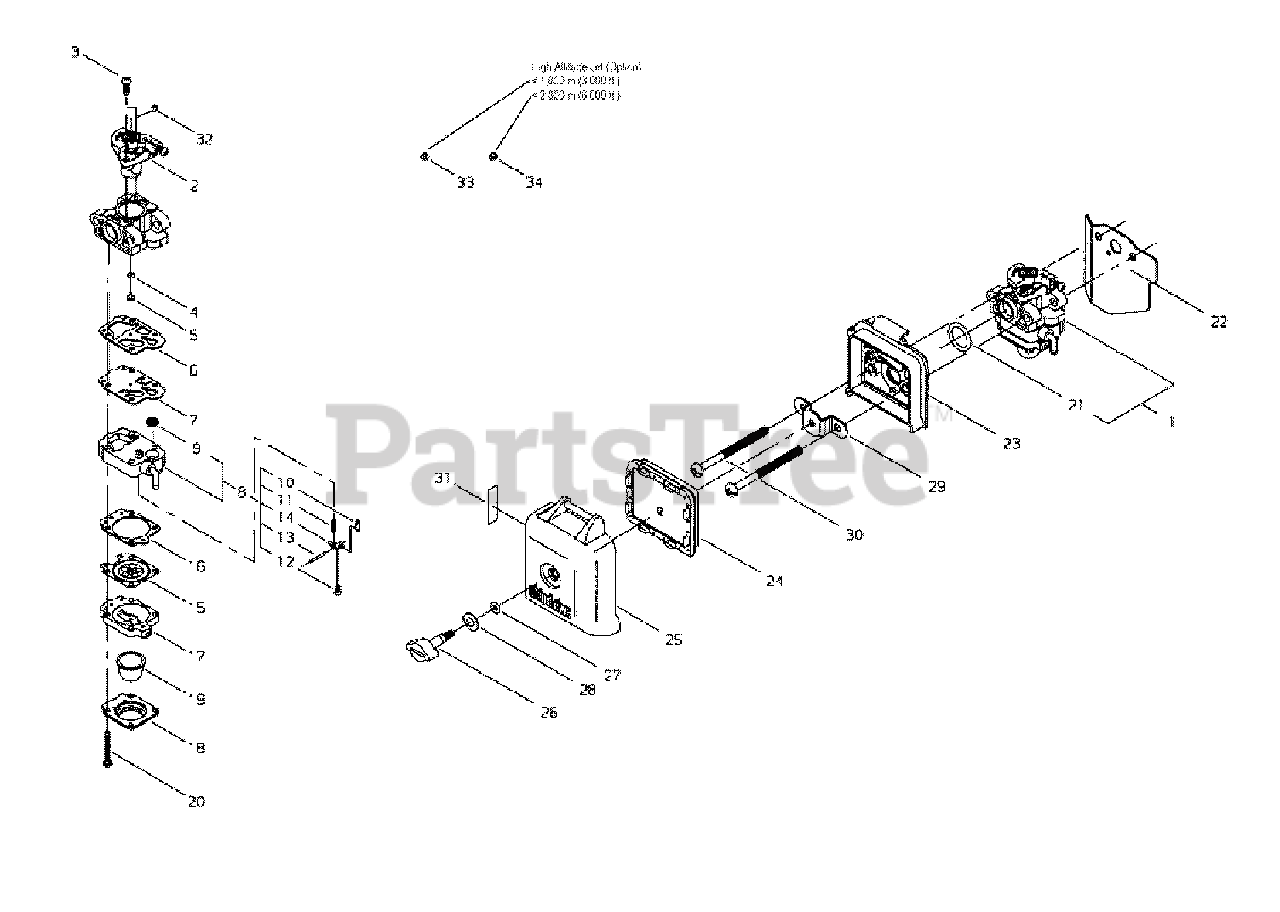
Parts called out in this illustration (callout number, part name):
1	CARBURETOR
2	VALVE, THROTTLE
3	SCREW
4	O-RING
5	JET, MAIN
6	GASKET, PUMP
7	DIAPHRAGM, PUMP
8	BASE, PURGE
9	STRAINER
10	VALVE, INLET NEEDLE
11	SPRING, METERING LEVER
12	SCREW, METERING LEVER PIN
13	PIN, METERING LEVER
14	LEVER, METERING
15	DIAPHRAGM, METERING
16	GASKET, METERING
17	BASE, PURGE
18	RETAINER, PURGE BULB
19	BULB, PURGE
20	SCREW, PUMP COVER
21	O-RING - 15
22	SHIELD, INTAKE
23	CASE, AIR FILTER
24	FILTER, AIR - HEAVY DUTY
25	COVER, AIR FILTER
26	THUMBSCREW
27	O-RING
28	WASHER - CONICAL
29	PLATE, PREVENT
30	SCREW - 5X60
31	LABEL - CHOKE
32	PLUG
33	JET, MAIN
34	JET, MAIN - 1000M
